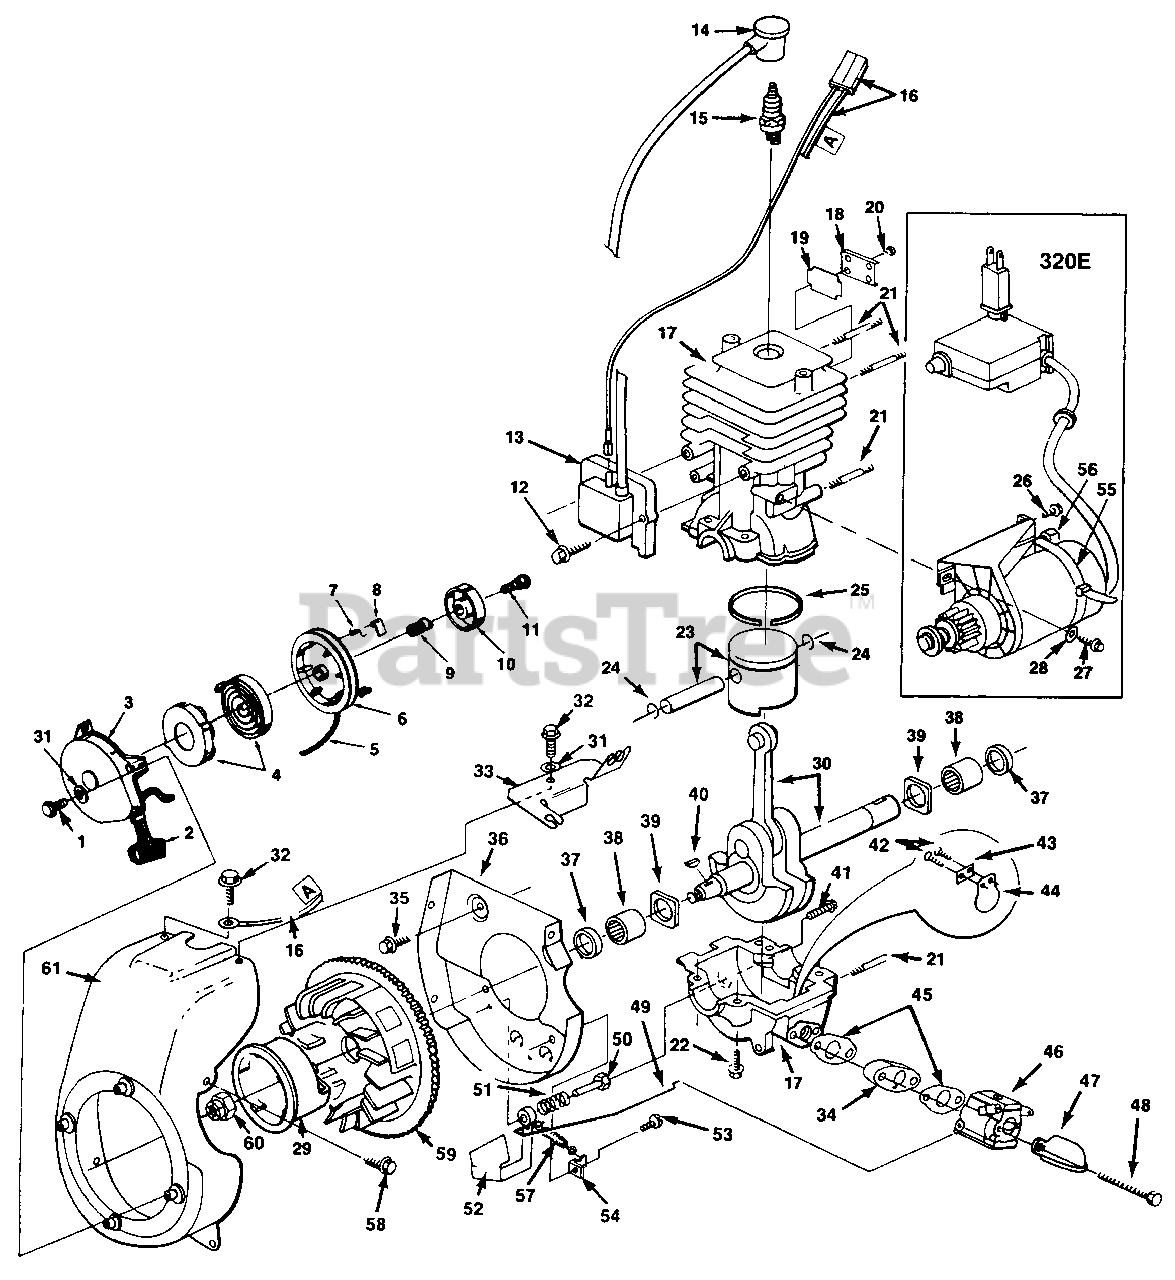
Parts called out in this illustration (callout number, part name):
1	SCREW- Hex hd 1/4-20 x 1/2"
2	HANDLE ASSEMBLY
3	STARTER HOUSING ASSEMBLY
4	SPRING & KEEPER ASSEMBLY
5	ROPE- Starter 75"
7	SPRING- Dog
9	SPRING- Brake
12	SCREW-Thd. rolling
13	MODULE-Ignition
14	COVER-Spark
15	SPARK PLUG (CJ8Y)
16	LEAD-Electrical
17	CYLINDER & CRANKCASE
18	COVER- Cylinder
20	SCREW- Thd. rolling 8-32 x 5/16
21	STUD- Thd. rolling
22	SCREW- Sems hex hd 1/4-20 x 1 1/2
23	PISTON & PIN ASSEMBLY
24	RING- Pin retaining
25	PISTON RING
26	SCREW- 10-24 x 3/4
27	SCREW- (320E)
28	WASHER- (320E)
29	HUB- Starter
30	CRANKSHAFT ASSEMBLY
31	WASHER-Lock 1/4"
32	SCREW-Thd forming 1/4-20 x 1"
33	BRACKET
34	SPACER- Carburetor
35	SCREW-Thd forming 10-24 x 1/2"
36	PLATE-Fan housing
37	SEAL-Shaft
38	BEARING- Needle
39	WASHER- Thrust
40	KEY- Woodruff
41	SCREW- Sems hex hd 8-32 x 3/4"
42	SCREW- Thd #8 x 1"
43	REED- RETAINER
44	REED VALVE
45	GASKET- Carburetor
46	CARBURETOR WALBRO (HDA 59)
47	SHIELD- Carburetor
48	SCREW- Thd forming 10-24 x 2.875
49	THROTTLE ROD
50	PIN- Pivot
52	VANE- Governor
53	SCREW- Hex hd. 8-18 x .375
54	TAB- Gov. Adj
55	STRAP- Tie
56	NUT- Hex 5-16 x 18
57	SPRING- Extension
58	SCREW- Tap hex hd #10 x 3/8"
60	NUT- 7/16-20 hex
61	HOUSING- Fan
